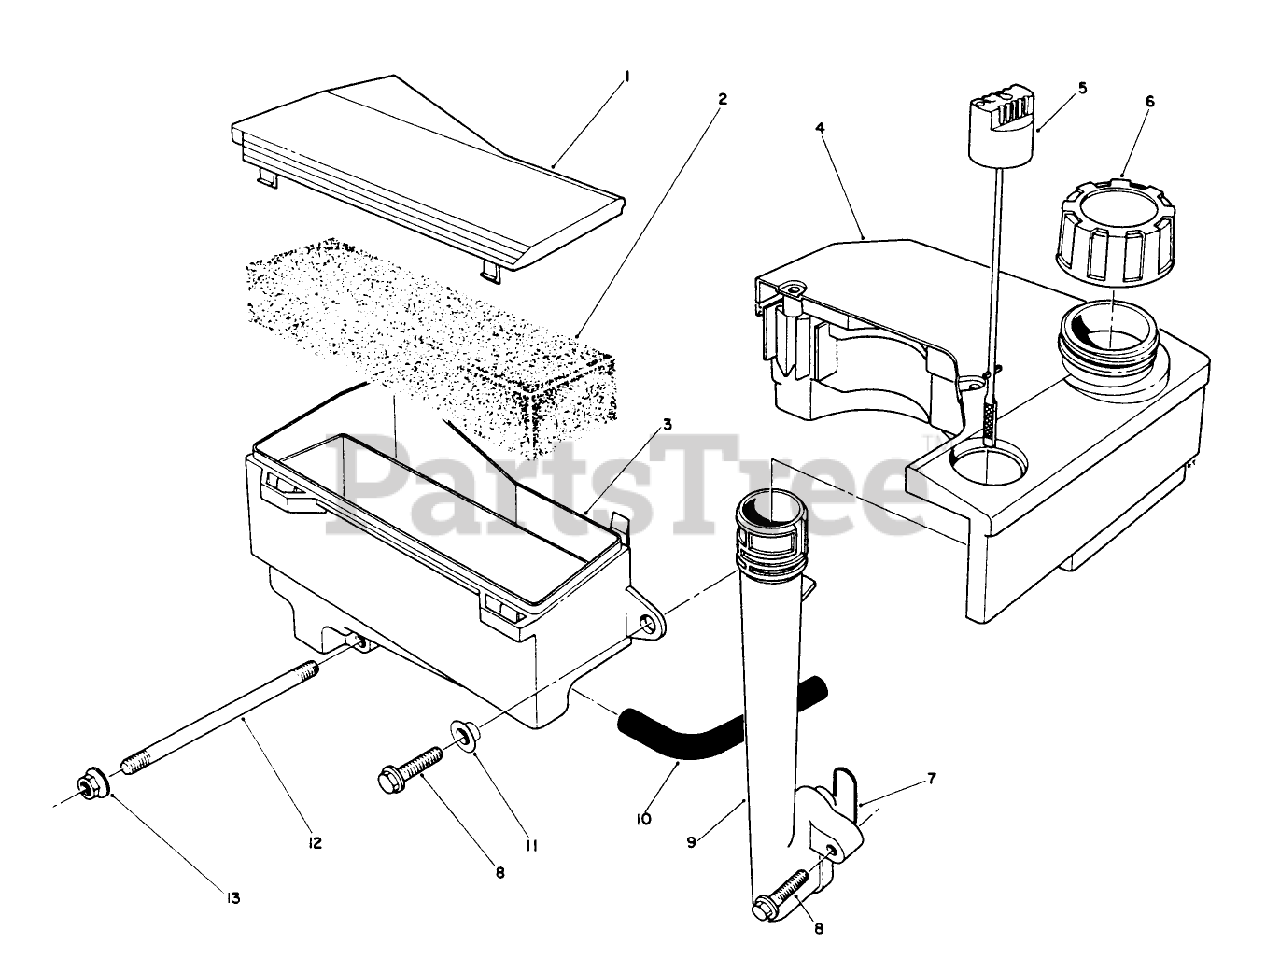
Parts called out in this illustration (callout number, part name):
1	AIR CLEANER CAP
3	Body-Air Cleaner
4	TANK ASM
6	GAS CAP ASM
7	O-RING
11	SPACER
